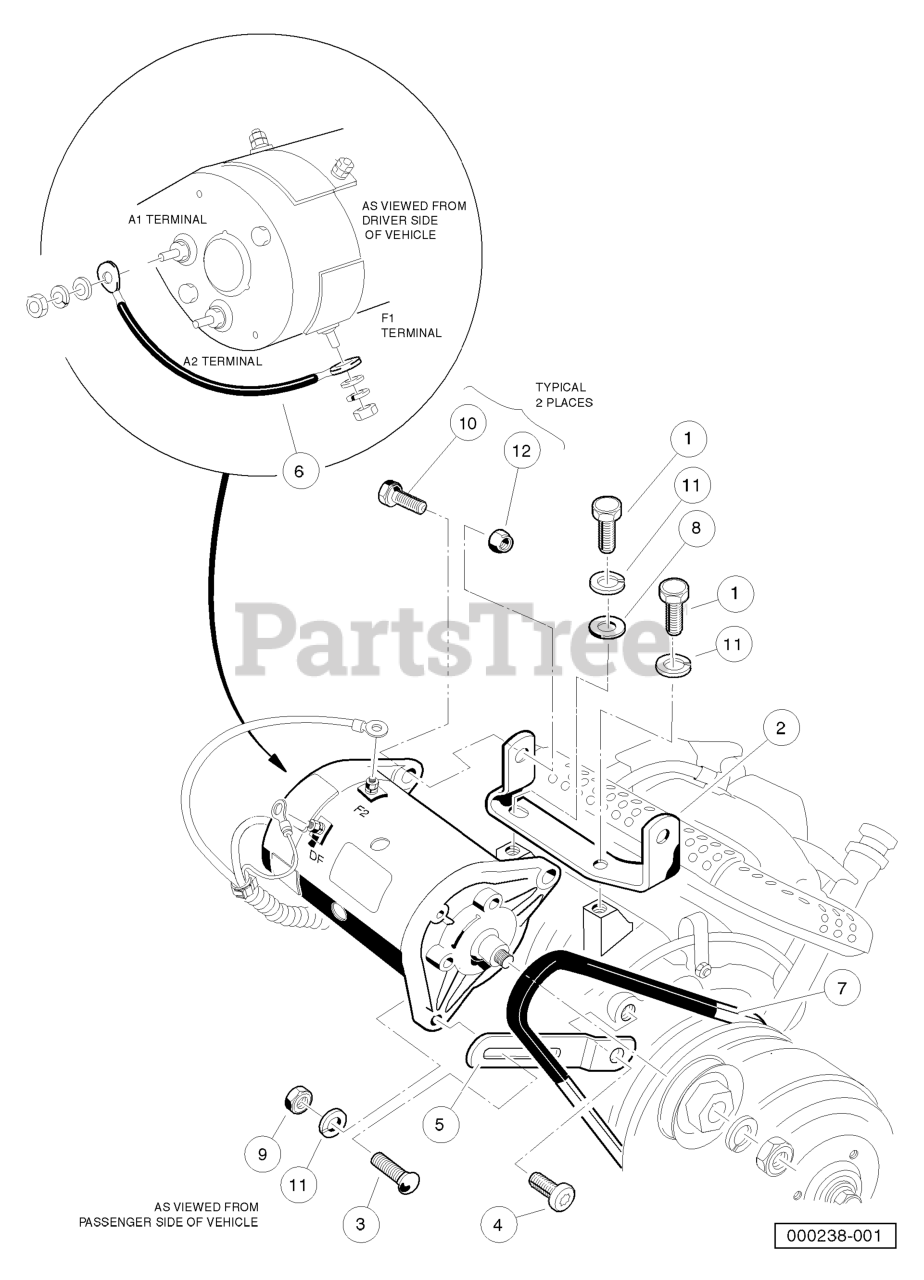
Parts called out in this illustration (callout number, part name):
1	SCREW, M8-125 X 22 HEX GR.8.8
2	BRACKET, FE290 S/G MOUNTING
3	BOLT, 5/16-18 RD HD SQ NECK
4	SCREW, M8-1.25 X 18MM TORX
5	BRACKET, S/G-ADJUSTABLE
6	WIRE ASSY, #6 GREEN
7	BELT, STARTER-GENERATOR
8	WASHER, 5/16 TYPE A FLAT
9	NUT, 5/16-18 HEX
11	LOCKWASHER, 5/16 SPLIT
12	LOCKNUT, 3/8-16 HEX
